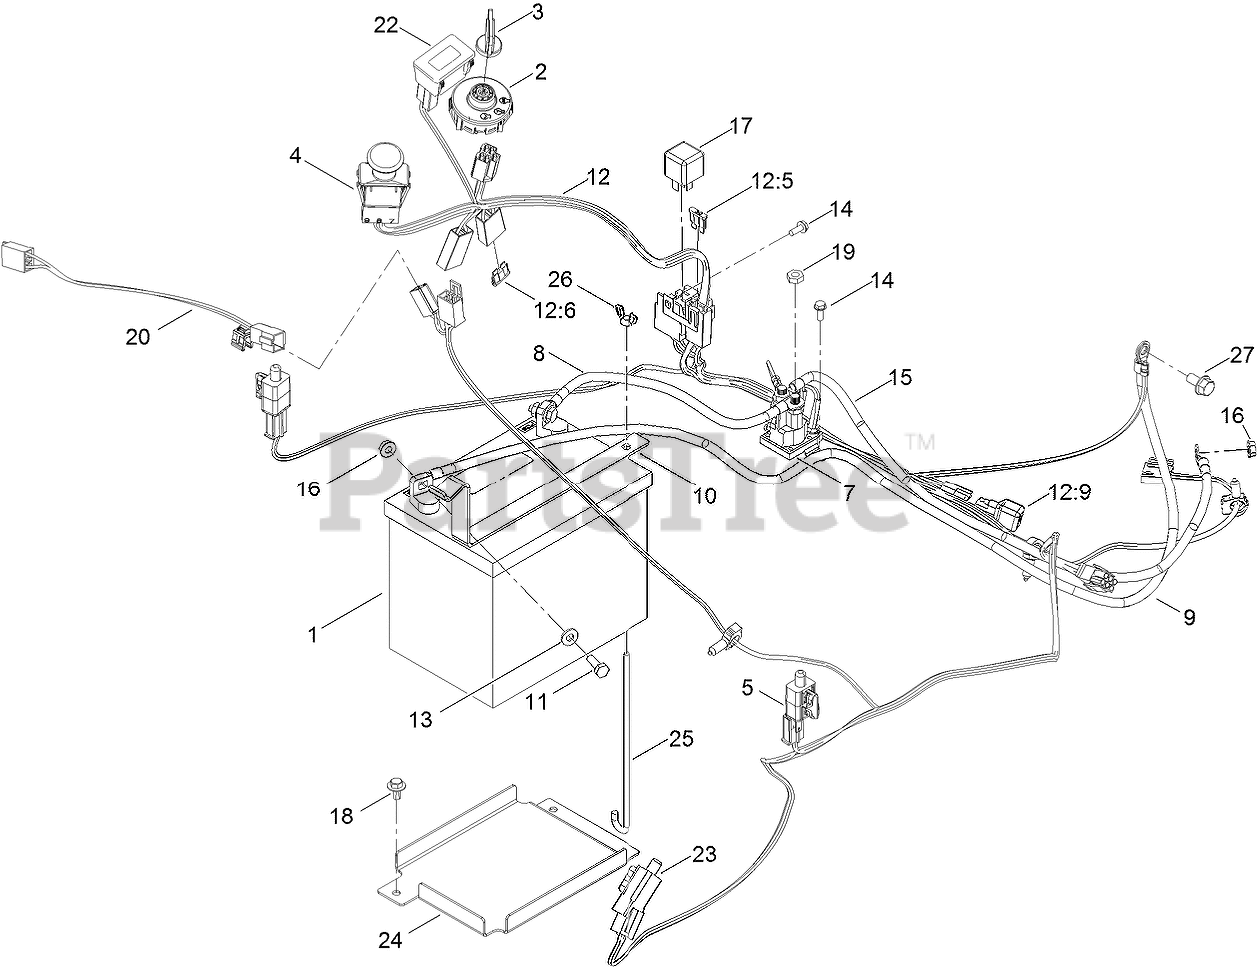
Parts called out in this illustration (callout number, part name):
1	BATTERY
2	SWITCH-IGNITION
3	KEY-IGNITION
4	SWITCH-PTO
5	SWITCH
7	SOLENOID
8	CABLE-BATTERY, POSITIVE
9	CABLE-BATTERY, NEGATIVE
10	STRAP-BATTERY
11	SCREW-HH
12	HARNESS-WIRE
12:5	FUSE-BLADE, 30 AMP
12:6	FUSE-BLADE, 25 AMP
13	WASHER-FLAT
14	SCREW-TAPTITE
15	WIRE-21 INCH
16	NUT-HF
17	RELAY
18	SCREW-HHFTF
19	NUT-JAM
20	HARNESS-WIRE
22	HOURMETER
23	SWITCH-REVERSE
24	TRAY-BATTERY
25	BOLT-HOLDDOWN
26	WINGNUT
27	SCREW-HHF
